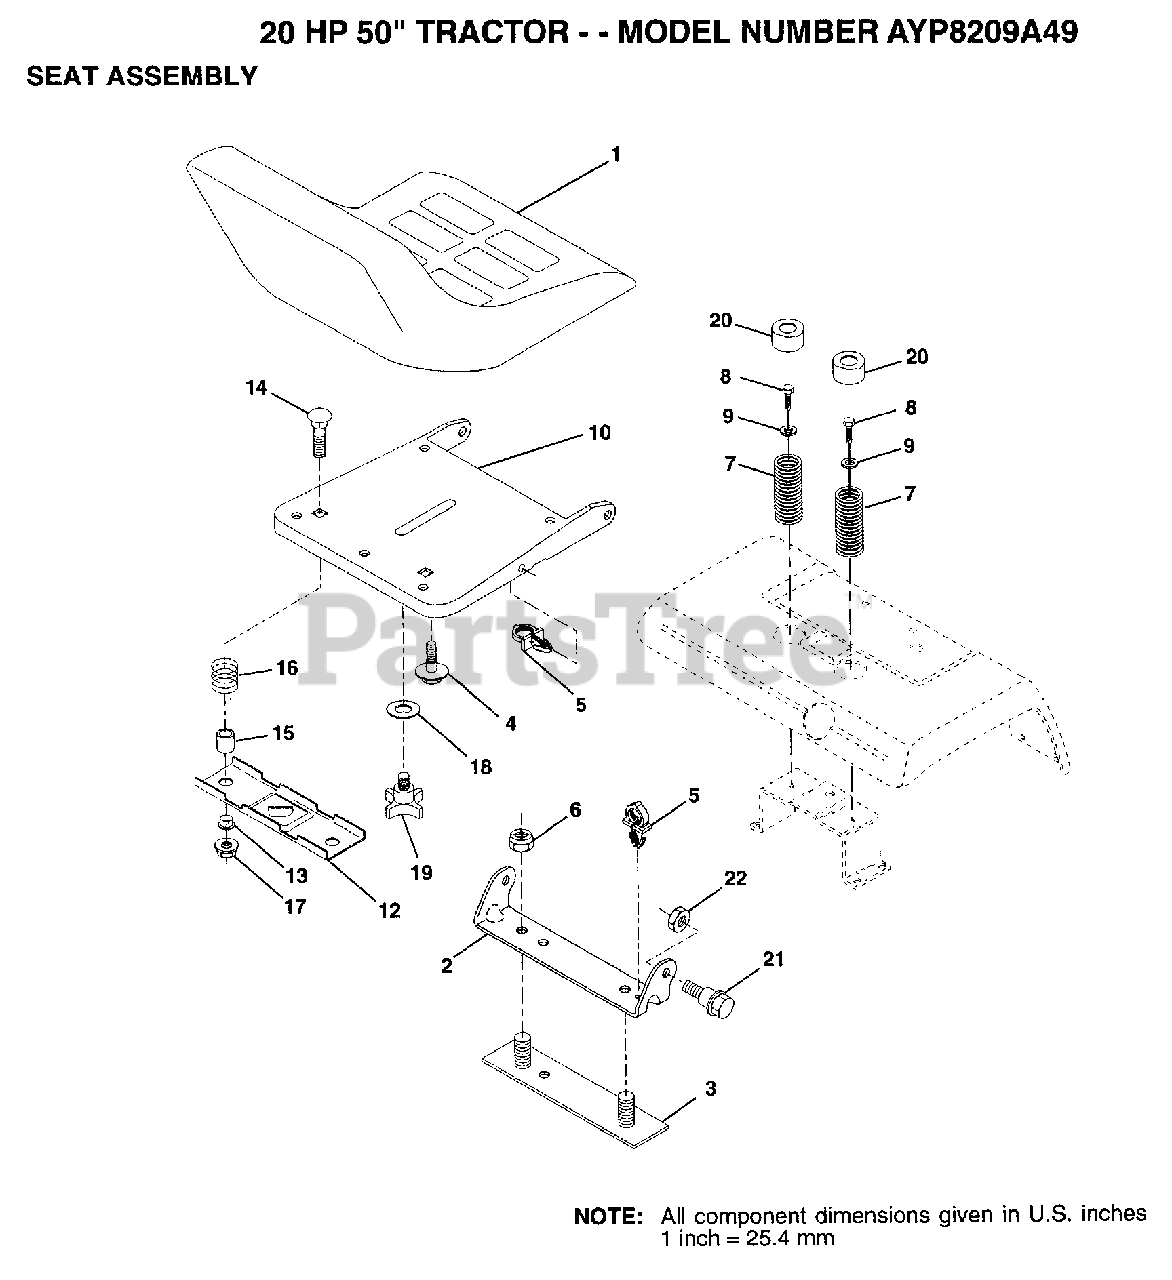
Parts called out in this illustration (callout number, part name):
2	BRACKET PVT SEAT
3	STRAP ASM FENDER
4	"BOLT,SHOULDER"
5	CLIP PUSH - IN
6	NUT
7	SPRING COMPRESSIO
8	SCREW LT
9	WASHER
12	BRKT SWITCH
13	BUSHING
15	SPACER SPLIT
16	SPRING COMPRESSED
18	WASHER
19	"KNOB 1/2"" YT"
20	CAP SPRING
21	BOLT.SHLD.5/16-18
